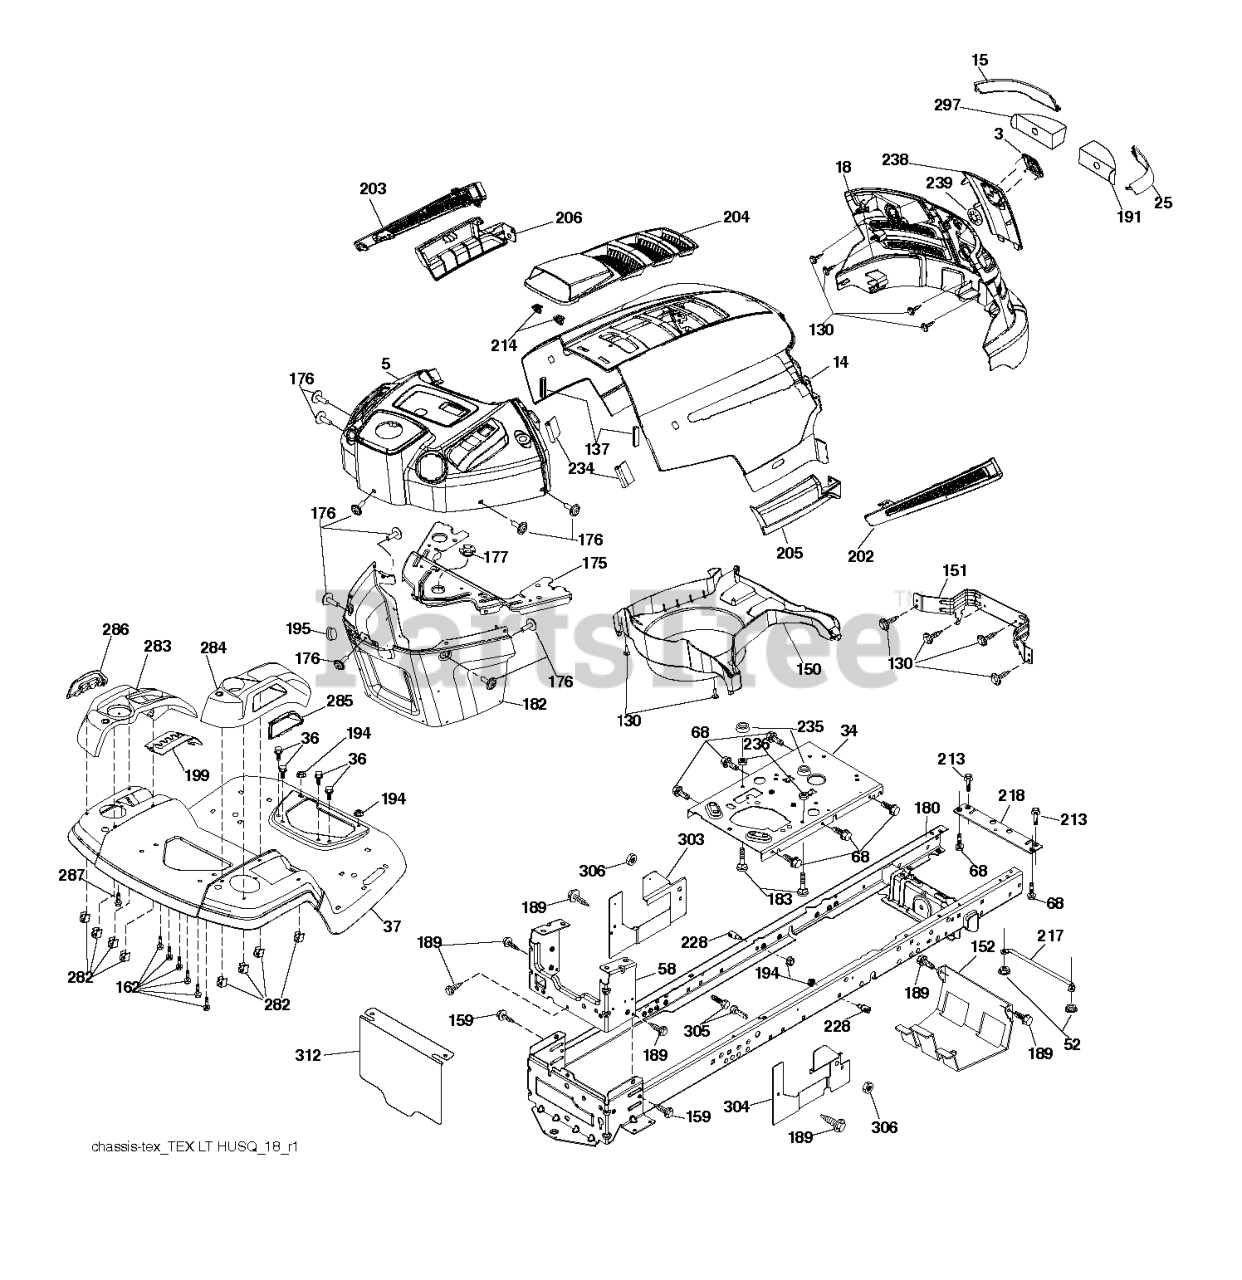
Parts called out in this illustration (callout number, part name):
3	RP LOGO
5	DASH
14	HOOD
15	LENS.HUSQVARNA LT.LH
18	RP GRILLE/LENS ASM.
25	LENS.HUSQVARNA LT.RH
34	PLATE.ENGINE.WELDED.CHASSIS
36	SCREW 5/16"
37	RP FENDER.TLT.FS.W/CPH.422
52	LOCKNUT
58	DRAWBAR UPPER 2PC SMALL FENDER
68	Screw 5/16-18 x 1/2 Hex, Self Tapping 5/16-18 x 1/2
130	SCREW.#10 X 0.750.BOS
137	BUMPER DASH
151	BRACKET PIVOT
152	SHIELD.BROWNING.W/TEX
159	SCREW, 3/8-16X3/4
162	SCREW.HI-LO.CONSOLE
175	CROSSMEMBER
176	SCREW.#10-24X5/8.RN.QU
177	BUSHING STEERING
180	CHASS.WLDMNT.TL.12GA/2P.48/54
182	DASH.LOWER.PREDATOR LT
183	BOLT.5/16-18X1-1/4 FULL.THREAD
189	SCREW
191	INSERT.REFLECTIVE.RH.
194	NUT LOCK HEX FLANGE 5/16-18
195	PLUG DASH
199	PLATE.DECK.LIFT.HUSQ.LT
202	VENT SIDE HOOD RH
203	VENT SIDE HOOD LH
204	VENT TOP HOOD
205	SKIRT SIDE RH
206	SKIRT SIDE LH
213	BOLT
214	CLIP.RETAINER.TINNER.
217	ROD.PIVOT.HOOD
218	X-PIECE.HOOD.STOP.NON/
228	STUD.FASTNER.W/ANTI-ROTATE
234	BUMPER.HOOD.TEX.HUSQVARNA
235	SPACER FENDER
236	NUT.CENTERLOCK.5/16-
238	TRIM
282	CLIP.RETAINER.CONSOLE.LT.HUSQ
283	CONSOLE.DECK.LIFT.HUSQ.N/FR.GR
285	CONSOLE INSERT RH
286	CONSOLE.INSRT.LH.HUSQ.LT.BLACK
287	SCREW 1/4X20
297	INSERT REFLECTIVE
303	SHIELD CHASSIS LEFT
304	SHIELD CHASSIS RIGHT
305	BOLT
306	NUT LOCK FLG 3/8-16 UNC
